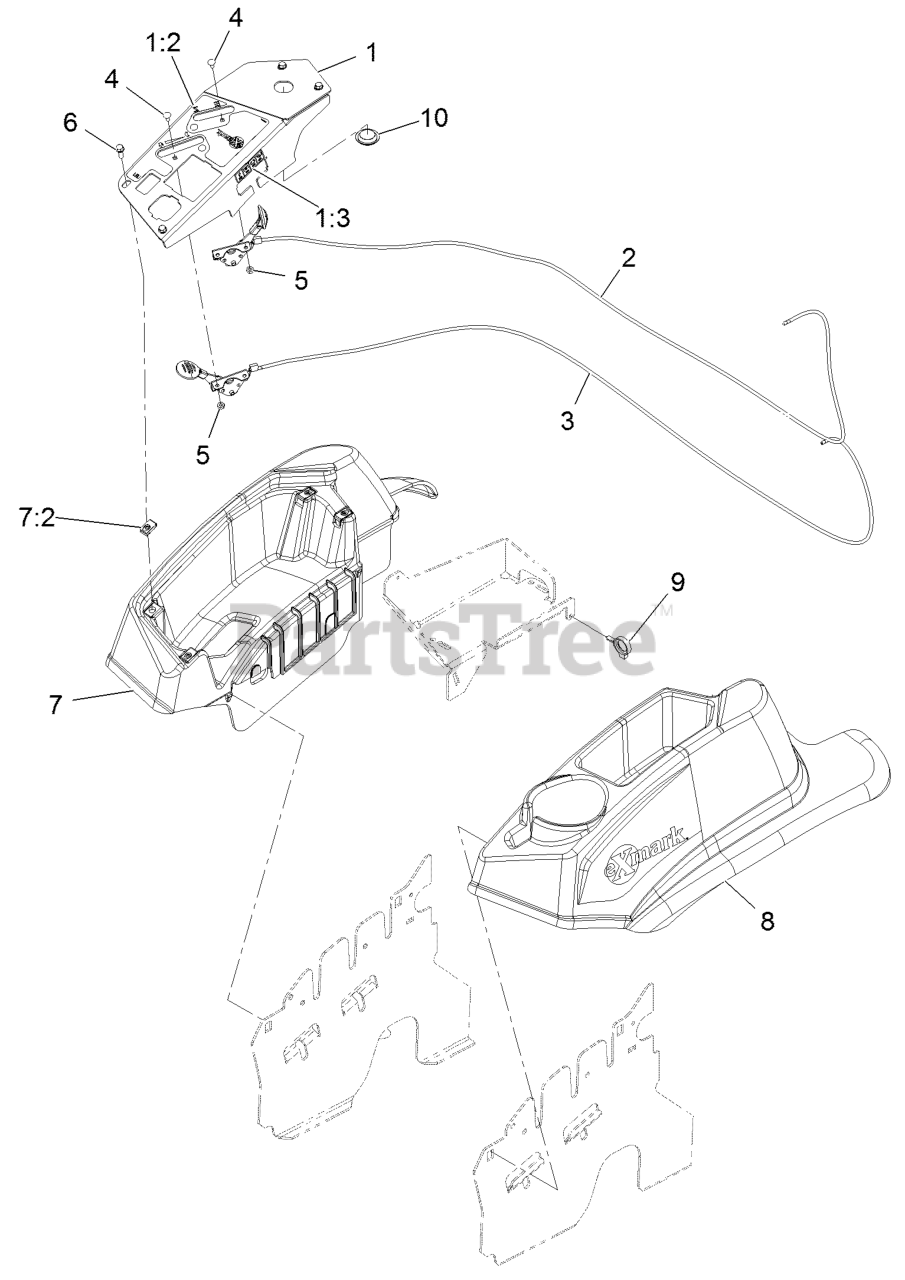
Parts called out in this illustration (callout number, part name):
1	Console,Panel W/Decal
1:2	Decal-Control Panel Non-Efi
1:3	Decal-Fuses
2	ASM, Choke Cable
3	ASM,Throttle Cable
4	Bolt-Carriage #10-24 X 1/2
5	Nut-Nyloc #10-24
6	Screw-Machine 1/4-20 X 3/4
7	Console,RH As ASM
7:2	Nut-Retainer-Panel 1/4-20
8	Console, LH As
9	Clamp-Hose
10	Plug,Plastic
